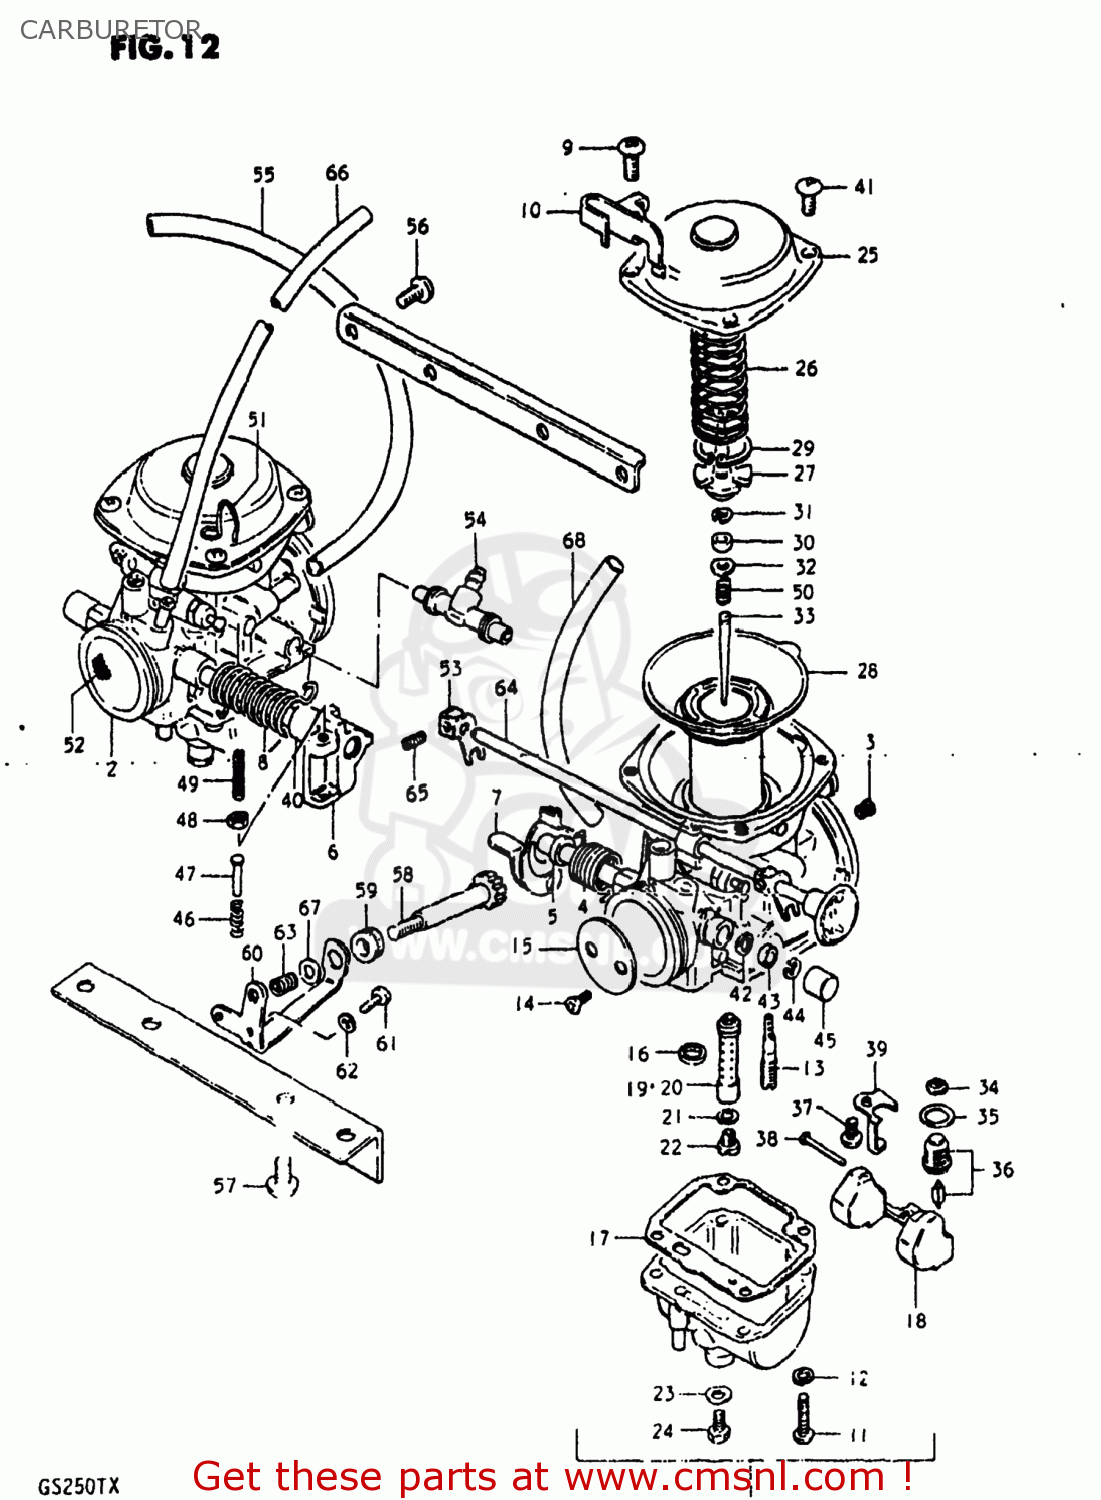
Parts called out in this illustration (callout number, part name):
1	CARBURETOR ASSEMBLY
2	CARBURETOR ASSEMBLY,LEFT (BS
3	JET,MAIN(135)
4	SPRING
5	RING
6	SHAFT ASSEMBLY
7	SHAFT ASSEMBLY
8	SPRING
9	SCREW
10	BRACKET
11	SCREW
12	LOCK WASHER
13	JET,PILOT(17.5)
14	SCREW
15	VALVE,THROTTLE
16	GASKET (NAS)
17	GASKET,FLOAT CAHMBER (NAS)
18	FLOAT
19	JET,NEEDLE
20	JET,NEEDLE
21	WASHER,NEEDLE NOZZLE
22	JET,MAIN(115)
23	GASKET (NAS)
24	PLUG,DRAIN
25	COVER,DIAPHRAGM
26	SPRING
27	HOLDER,GUIDE
28	DIAPHRAGM ASSEMBLY
29	E RING
30	RING
31	CLIP,NEEDLE
32	WASHER
33	NEEDLE JET
34	FILTER
35	O RING
36	VALVE ASSEMBLY,NEEDLE
37	SCREW
38	PIN,FLOAT
39	PLATE,NEEDLE VALVE FITING
40	RING,THROTTLE VALVE
41	SCREW
42	SEAL
43	GASKET,THROTTLE SHAFT (NAS)
44	E RING
45	CAP
46	SPRING,THROTTLE SCREW
47	PIN,THROTTLE LEVER
48	NUT
49	SCREW
50	SPRING
51	CLIP,HOSE
52	FILTER NET ASSEMBLY
53	LEVER
54	NIPPLE,CARBURETOR
55	HOSE
56	SCREW
57	SCREW
58	SCREW,THROTTLE STOP
59	BUSHING,THROTTLE ADJUSTER
60	BRACKET,THROTTLE ADJUST
61	SCREW
62	LOCK WASHER
63	SPRING
64	SHAFT,STARTER
65	SCREW
66	HOSE
67	WASHER
68	HOSE
